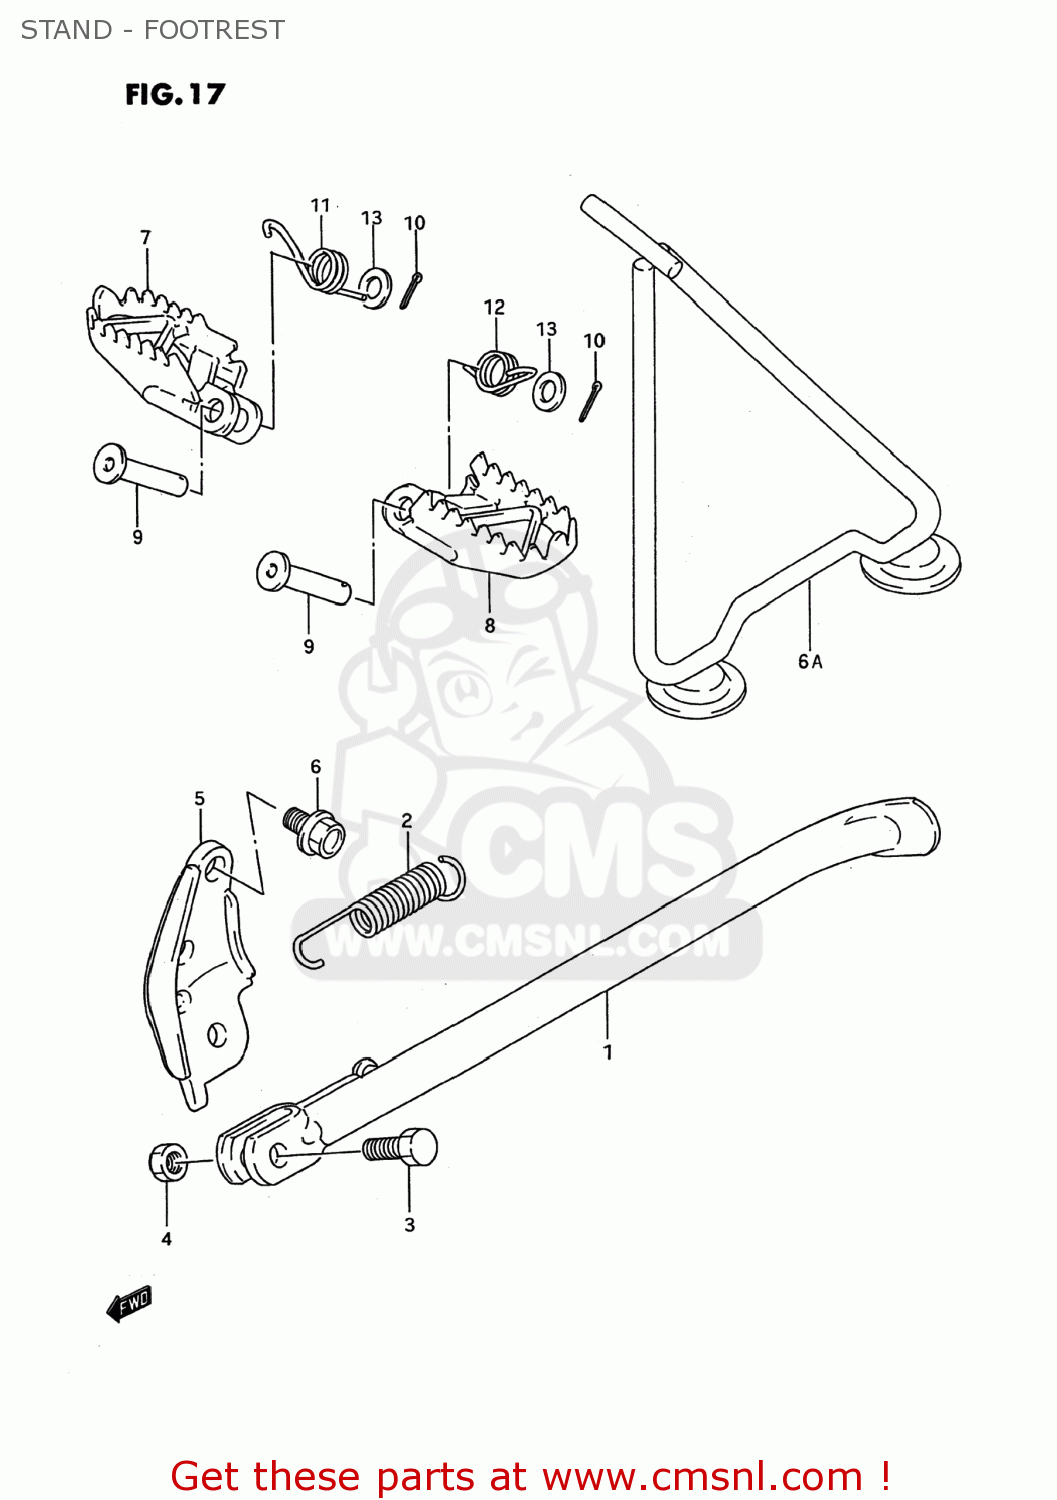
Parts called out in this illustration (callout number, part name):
1	STAND,PROP(BLACK)
2	SPRING
3	BOLT(10X30)
4	NUT
5	BRACKET,PROP STAND(BLACK)
6	BOLT
6A	STAND COMP
7	FOOTREST,R
8	FOOTREST,L
9	PIN(10X41.5)
10	PIN 25X20
11	SPRING
12	SPRING
13	WASHER
